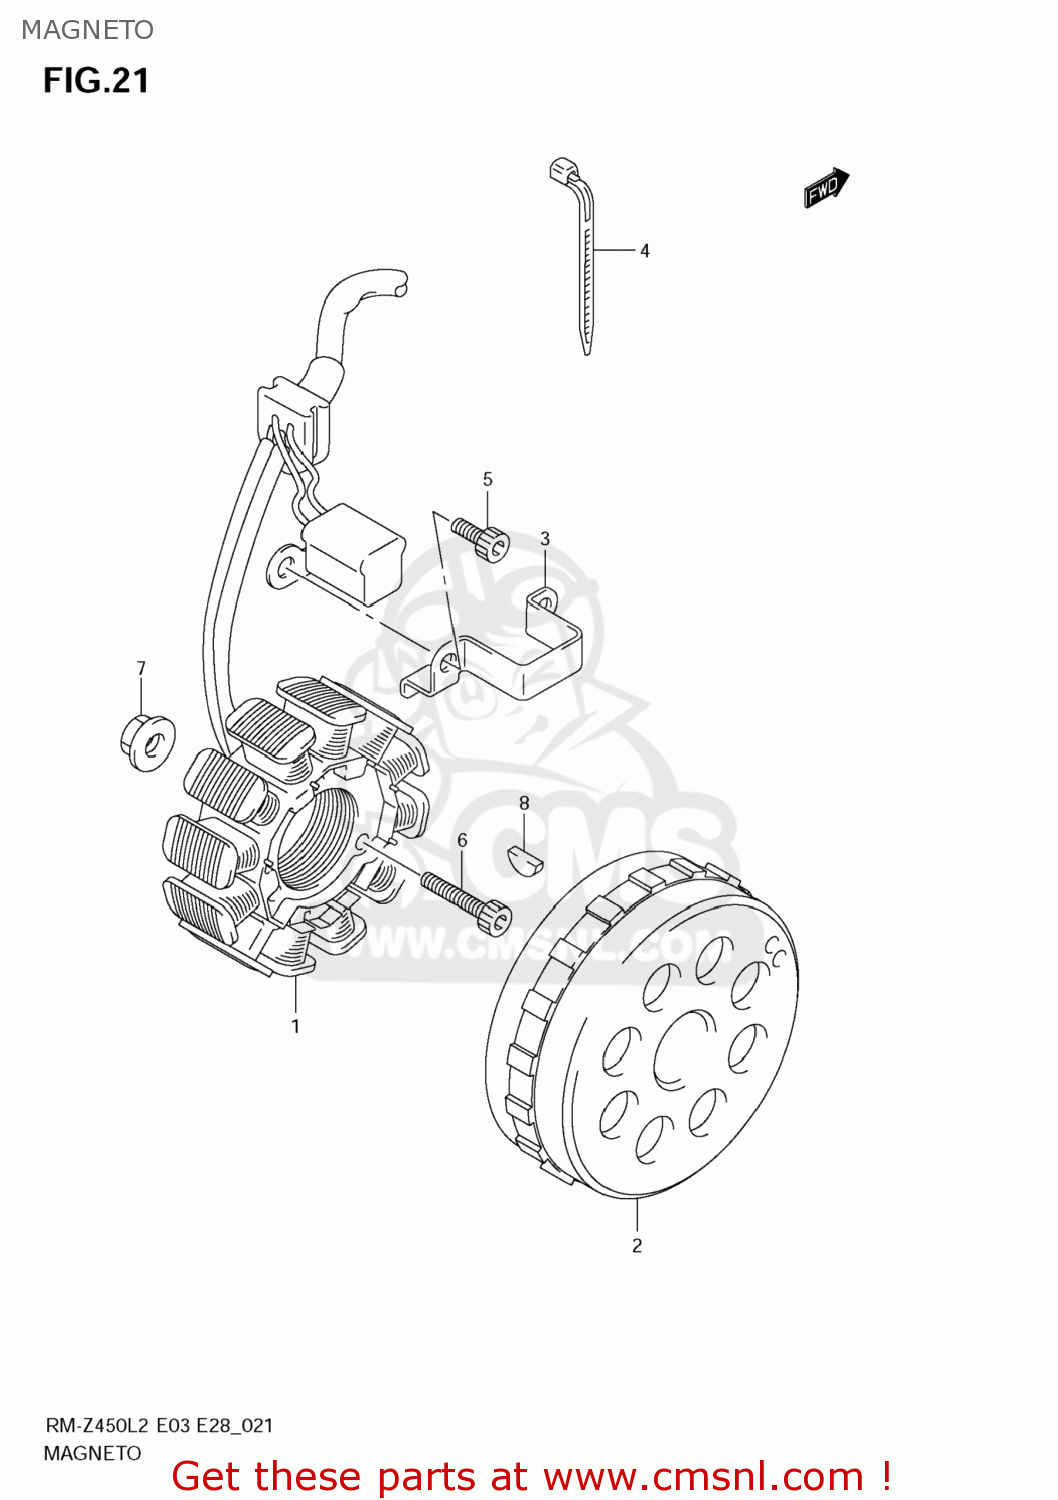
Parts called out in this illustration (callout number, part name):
1	STARTER ASSY
2	ROTOR ASSY
3	CLAMP,MAGNETO LEAD
4	CLAMP(L:125)
5	BOLT
6	BOLT
7	NUT
8	KEY
